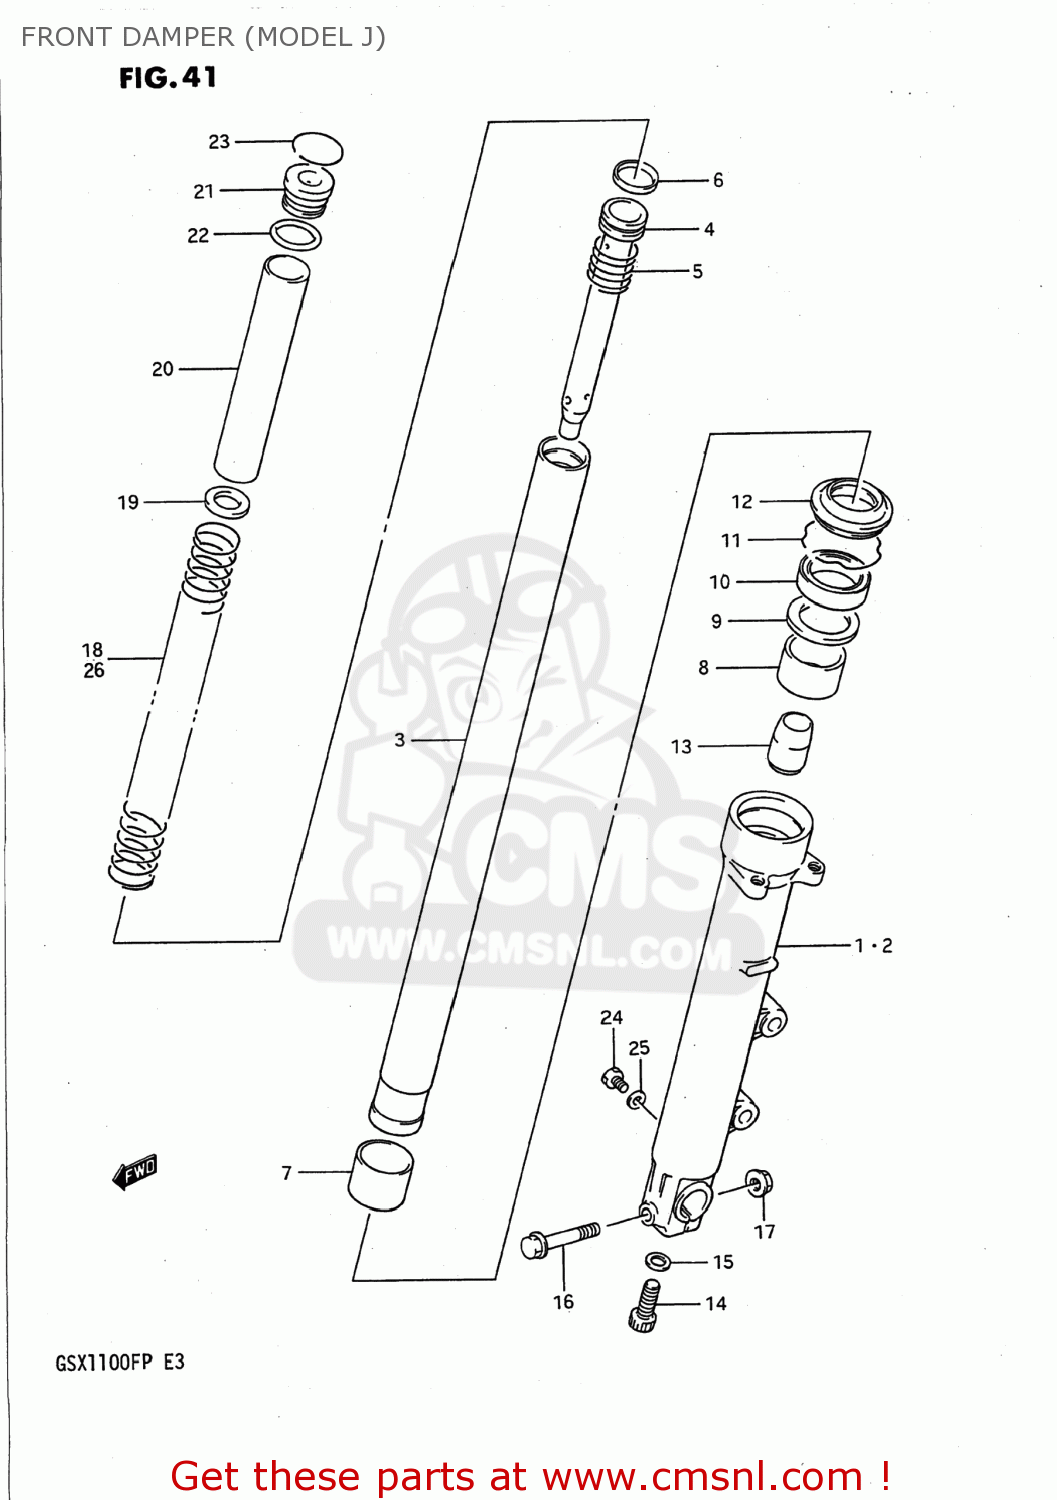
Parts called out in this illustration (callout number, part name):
1	TUBE,OUTER,RIGHT
2	TUBE,FORK,LEFT,OUTER
3	TUBE,FORK,INNER
4	CYLINDER
5	SPRING,REBOUND
6	RING,FRONT FORK PISTON
7	BUSH,SLIDE
8	BUSH,GUIDE
9	SPACER,SEAL
10	OIL SEAL,FRONT FORK
11	CIRCLIP,FORK OIL SEAL
12	BOOT
13	PIECE,OIL LOCK
14	BOLT(8X27)
15	GASKET (NAS)
16	BOLT 8X55
17	NUT
18	SPRING
19	JOINT,SPRING
20	SPACER,SPRING
21	SEAT,SPRING
22	O-RING
23	RING,STOPPER
24	BOLT
25	GASKET,DRAIN,PLUG (NAS)
26	SPRING,FRONT FORK
